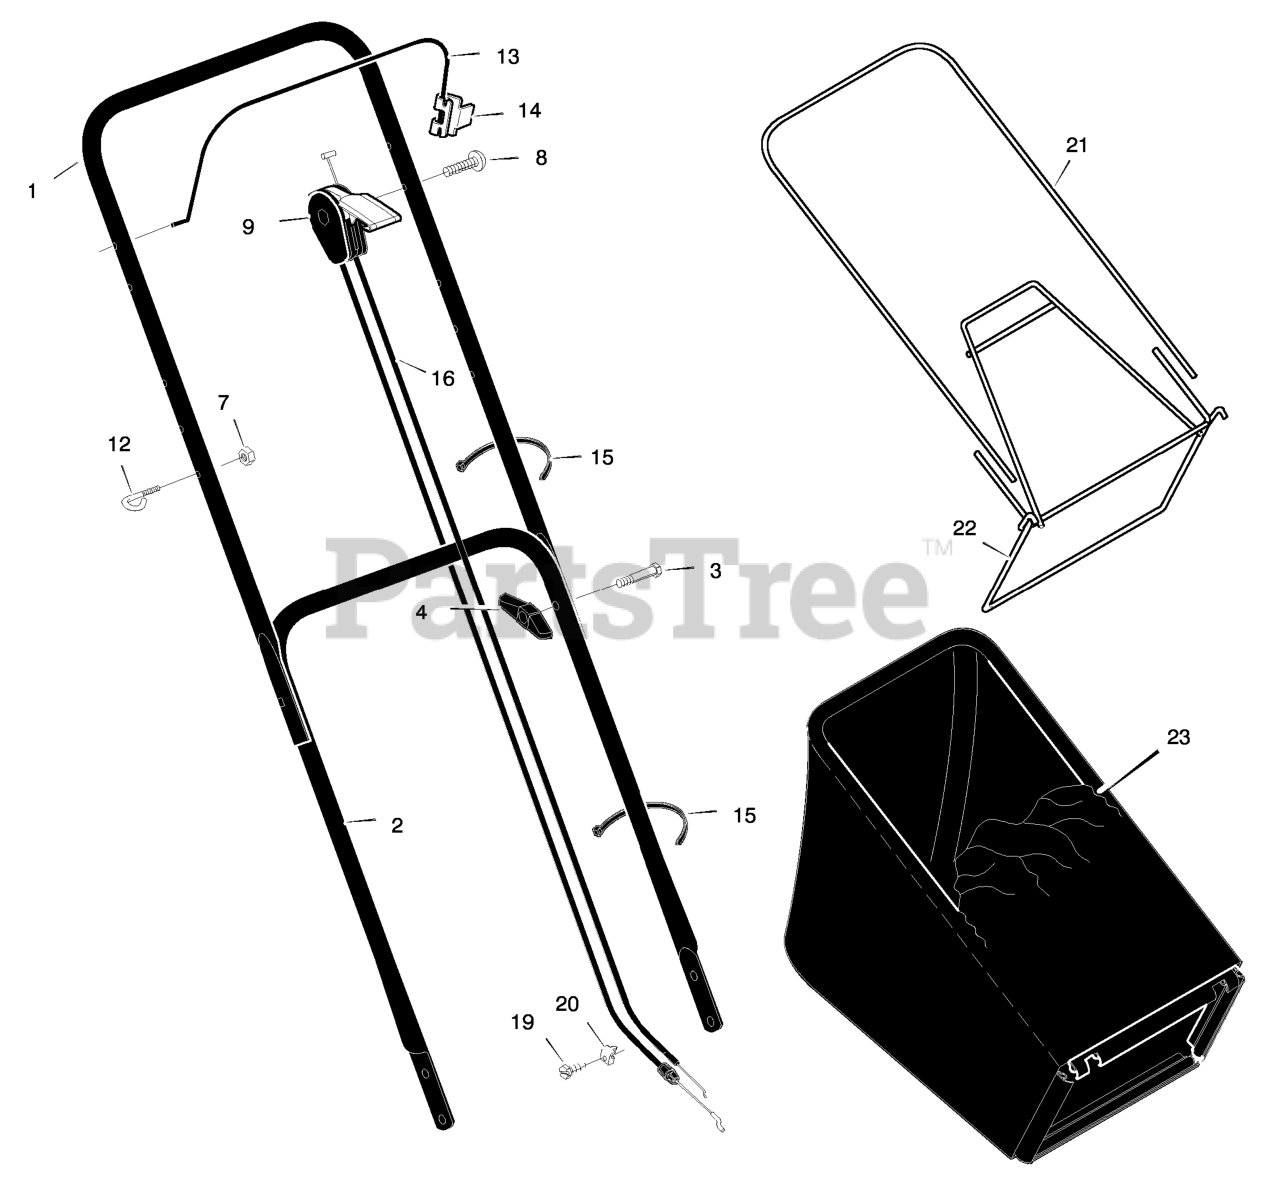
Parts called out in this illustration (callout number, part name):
1	Handle, Upper (Gray)
2	Handle, Lower (Gray)
4	Knob, Plastic
7	Locknut
9	Throttle Control
12	Guide, Rope
13	Engine Stop Lever
14	Bracket, Stop Lever
15	Fastener, Cable
16	Engine Stop Cable
21	Frame, Top
22	Frame Assembly
23	Bag, Cloth
